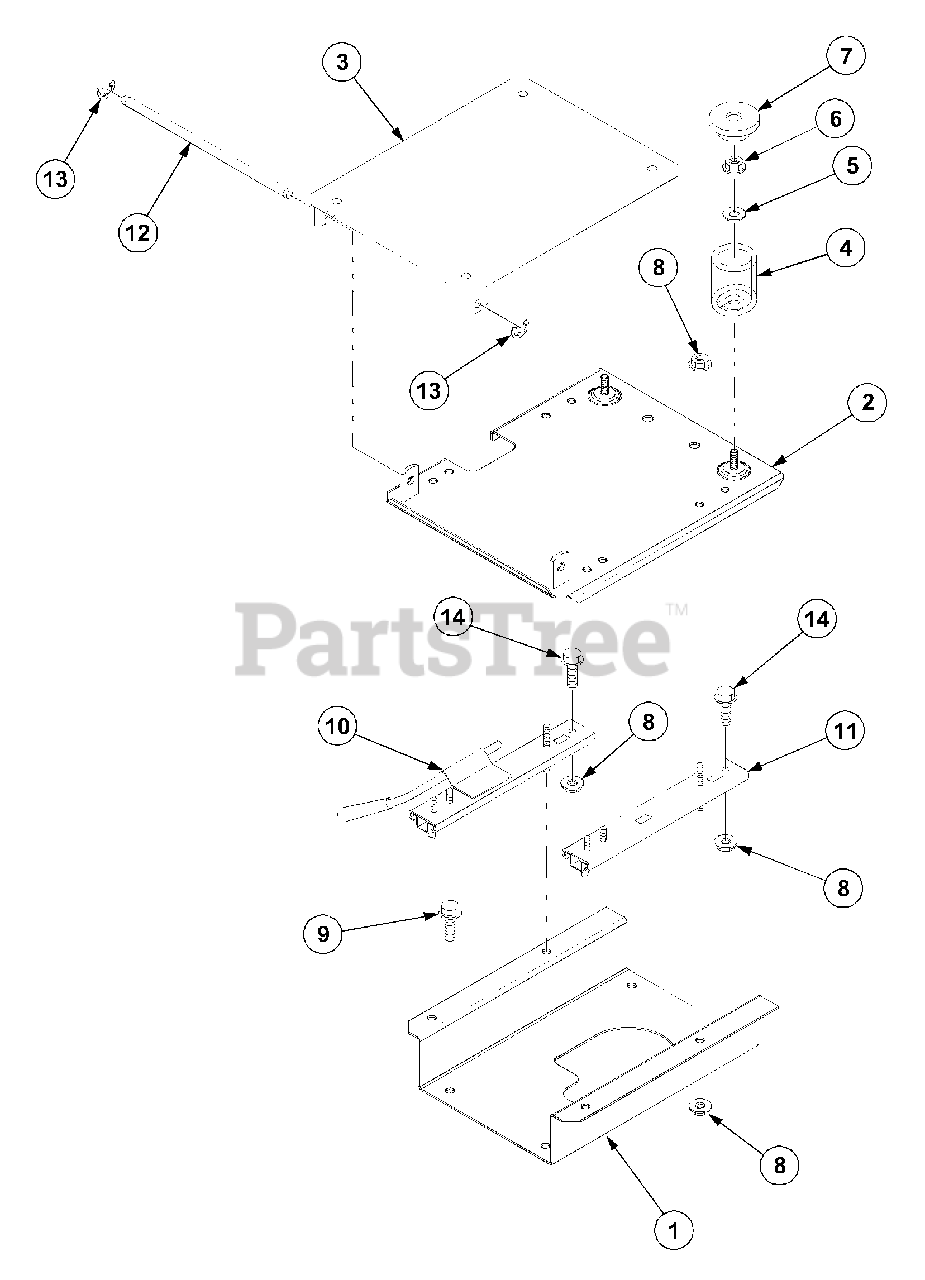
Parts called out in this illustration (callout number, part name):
4	Spring
9	Bolt,w/Washer
10	Adjuster,Seat
11	Adjuster,Seat
